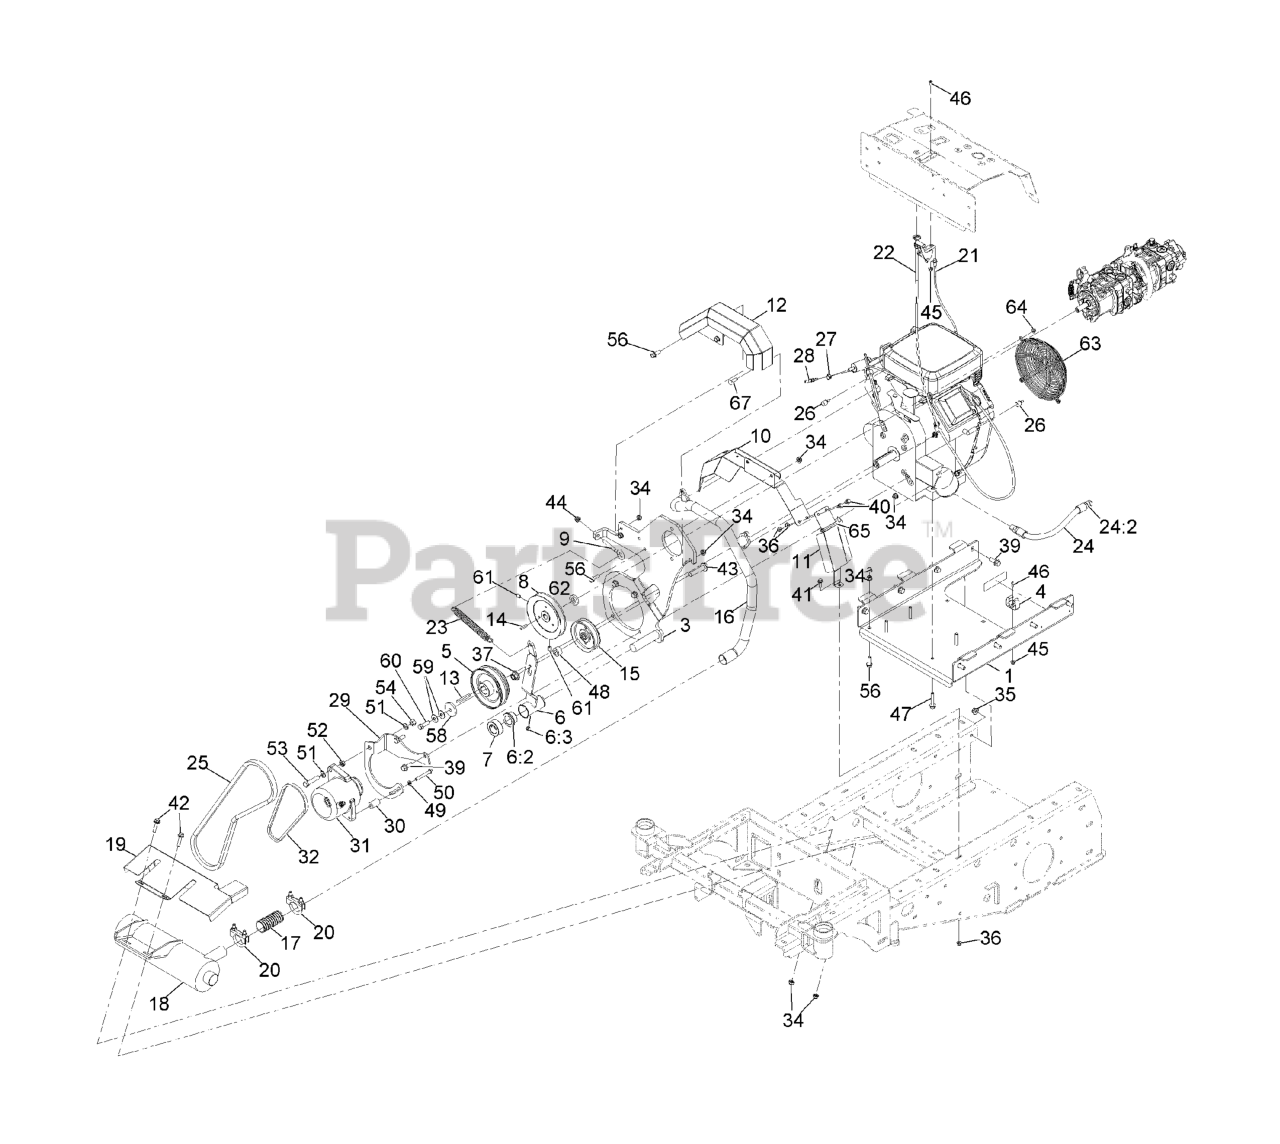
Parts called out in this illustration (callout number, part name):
1	Tray-Engine
3	Bracket-Engine, Pump [black]
4	Holder-Tool, Clip
5	Pulley-Double
6	Arm-Tension, ASM
6:2	BUSHING-FLANGE
6:3	FITTING-GREASE, ZERK
8	PULLEY-DRIVE, PUMP
9	Bolt-Eye
10	Guard, Lower Muffler
11	Guard, Lower Muffler
12	Guard-Pulley
15	PULLEY-IDLER, FLAT
16	Manifold-Exhaust
17	TUBE-EXHAUST, FLEX
18	MUFFLER
19	SHIELD-HEAT, MUFFLER
20	Clamp-Muffler
21	CABLE-THROTTLE
22	CABLE-CHOKE
23	SPRING-EXTENSION
24	ASM, Oil Drain Hose W/Plug
26	Tube-Heat Shrink, 1/2
27	CLAMP-HOSE
28	BARB-FUEL
29	Bracket-Alternator
30	TUBE-SUPPORT, ALTERNATOR
31	ALTERNATOR
32	Belt-V, 3L240
34	Nut-Hex Flange
35	Nut-Hex Flange
36	Nut-Hex Flange
37	Nut-Lock 1/2-13
39	SCREW-HHF
40	SCREW-HHF
41	Screw-HHF
42	SCREW-HHF
43	Screw-HHF
44	NUT-HF, NI
45	Nut-Hex Flange
46	Screw-HSBH
47	Screw-HHF
49	WASHER-LOCK
50	Screw-HH
51	Washer-Flat
52	Nut-Hex
53	Screw-HH
54	Nut-Lock, NI
56	SCREW-HHF
58	WASHER-PLAIN
59	WASHER-BELLEVILLE
60	Screw-HH
61	Setscrew-HSH
63	GUARD-WIRE, VANGUARD
65	TIE-CABLE
67	Bolt,Carriage,5/16-18X1,ST/ST 18-8
